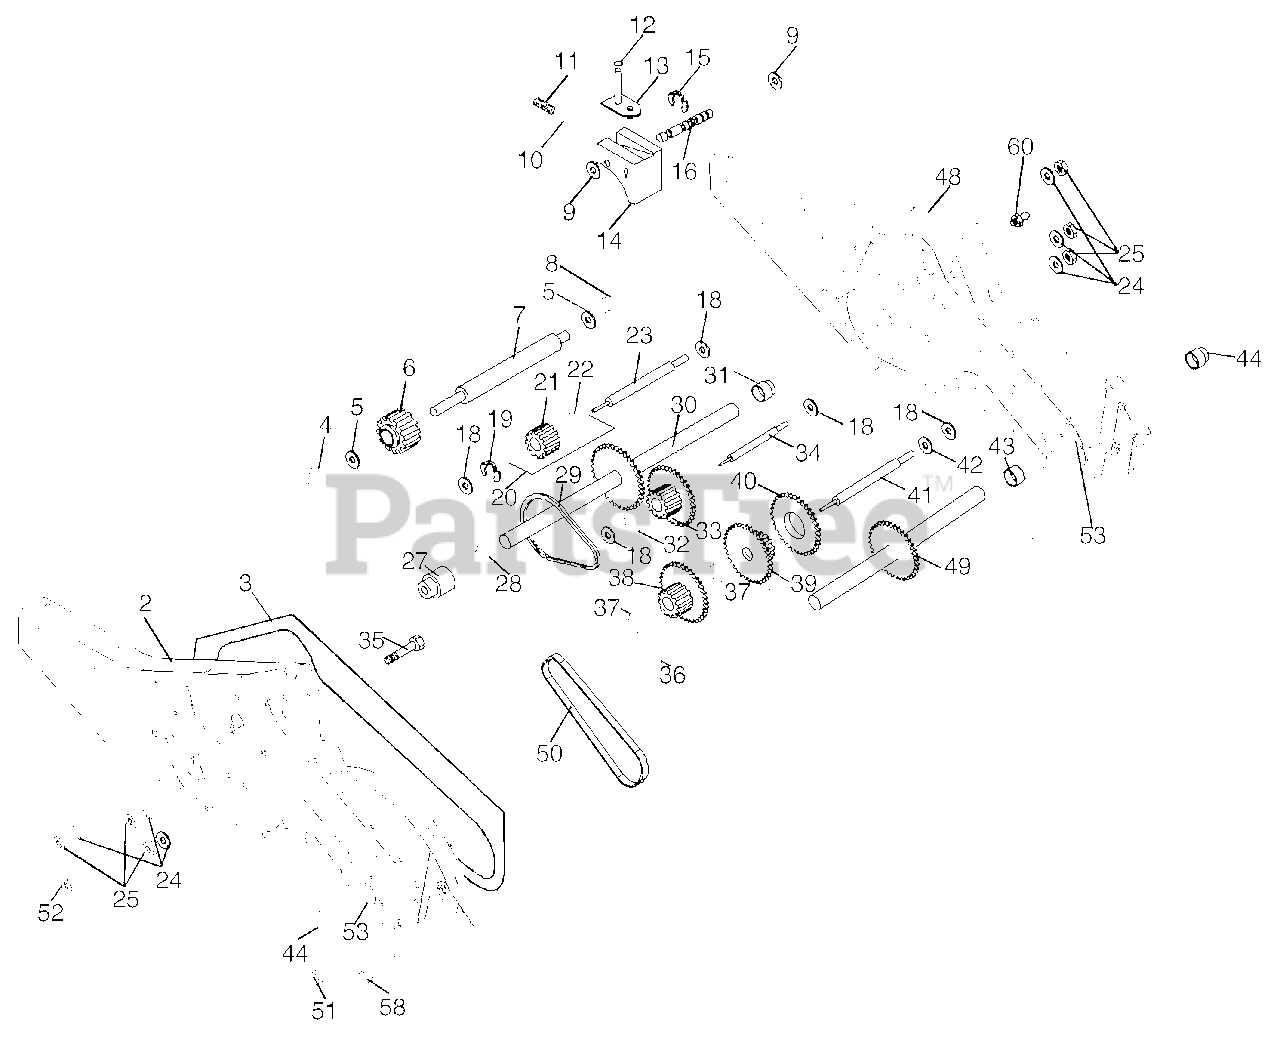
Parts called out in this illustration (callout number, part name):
1	Transmission Assembly
2	Gearcase, L.H. w/Bearing
3	Gasket, Gearcase
4	Bearing, Needle
5	Washer, Thrust 5/8 x 1.10 x 1/32
6	Pinion, Input
7	Shaft, Input
8	Bearing, Needle
9	Washer, Seal
10	Ball, Steel
11	Spring, Shift, Fork
13	Arm, Shift
14	Fork, Shift
15	Ring, Klip
16	Shaft, Shift
19	Ring, Klip
20	Gear, Assembly, Reverse Idler
21	Gear, Reverse Idler
22	Bearing, Needle
23	Shaft, Reverse Idler
24	Washer, Lock 7/16
25	Nut, Hex 7/16-20
27	Bearing, Shaft, Ground Drive L.H.
28	Spacer 0.765 x 1.125 x 1.23
29	Chain #35-50 Pitch
30	Ground Shaft Assembly
31	Bearing, Shaft, Ground Drive R.H.
32	Spacer 0.70 x 1.00 x 1.150
33	Sprocket and Gear Assembly
34	Shaft, Reduction (2nd)
35	Screw, Whiz, Lock 5/16-18 x 3-1/2
36	Sprocket Assembly w/Bearing
37	Bearing, Needle
38	Sprocket, Tine
39	Gear, Cluster, Red 1st & 2nd
40	Gear, Reverse
41	Shaft, Reduction (1st)
42	Washer, Thrust
43	Spacer 1.01 x 1.75 x 0.760
44	Seal Asm, Oil
48	Gearcase, R.H. w/Bearing
49	Shaft, Tine
50	Chain, Roller #50-50 Pitch
51	Screw 1/4-20 x 1/2
52	Nut, Hex 5/16-18
53	Kit, Bearing
58	Bolt Shoulder 1/4-20 unc x .875
60	Fitting Grease
